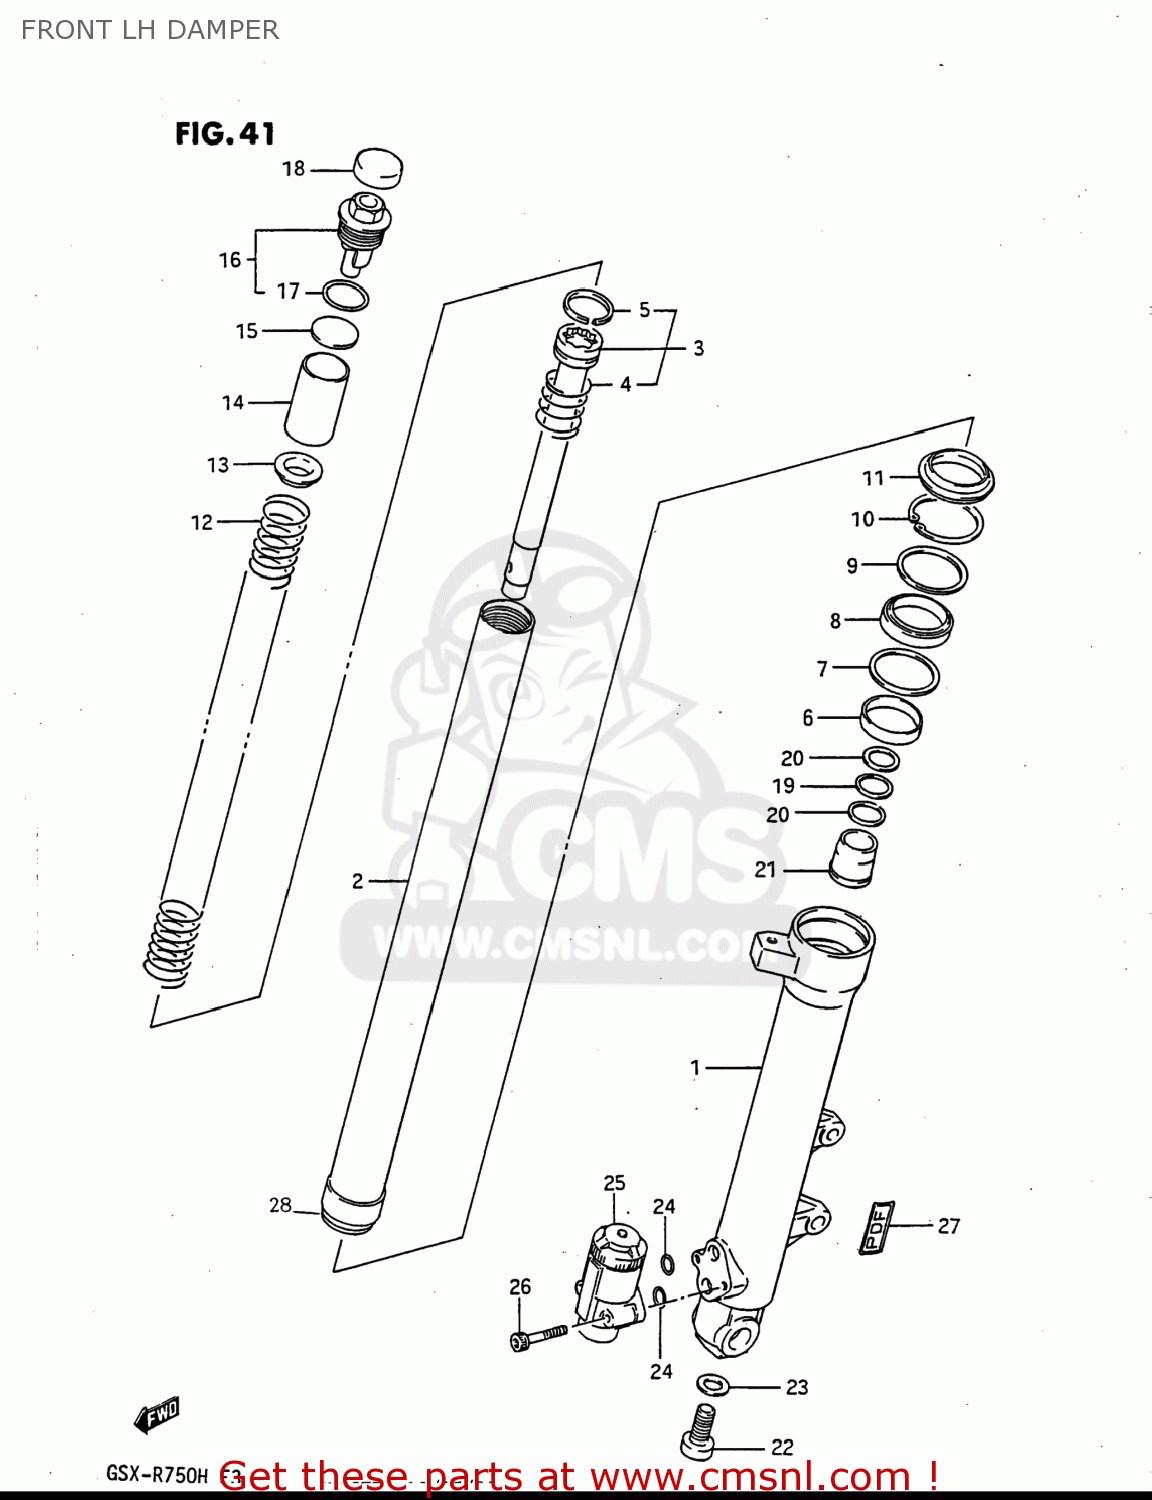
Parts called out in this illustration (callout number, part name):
1	TUBE,OUTER,LEFT
2	TUBE,FORK INNER
3	CYLINDER,FRONT FORK
4	SPRING,FORK REBOUND
5	RING,FR FORK PISTON
6	METAL,SLIDE
7	WASHER,FORK OIL SEAL
8	OIL SEAL,FRONT FORK
9	WASHER,FORK OIL SEAL
10	RING,OIL SEAL STOPPER
11	DUST SEAL,FRONT FORK
12	SPRING,FRONT FORK
13	WASHER
14	SPACER
15	WASHER,FR FORK SPRING
16	CAP,FORK INNER TUBE
17	O RING
18	CAP,FORK INNER TUBE
19	WASHER,OIL LOCK PIECE
20	SPRING,FORK OIL LOCK PIECE
21	PIECE,OIL LOCK
22	BOLT(14X25)
23	GASKET (NAS)
24	O RING
25	PDF ASSEMBLY
26	BOLT
27	EMBLEM
